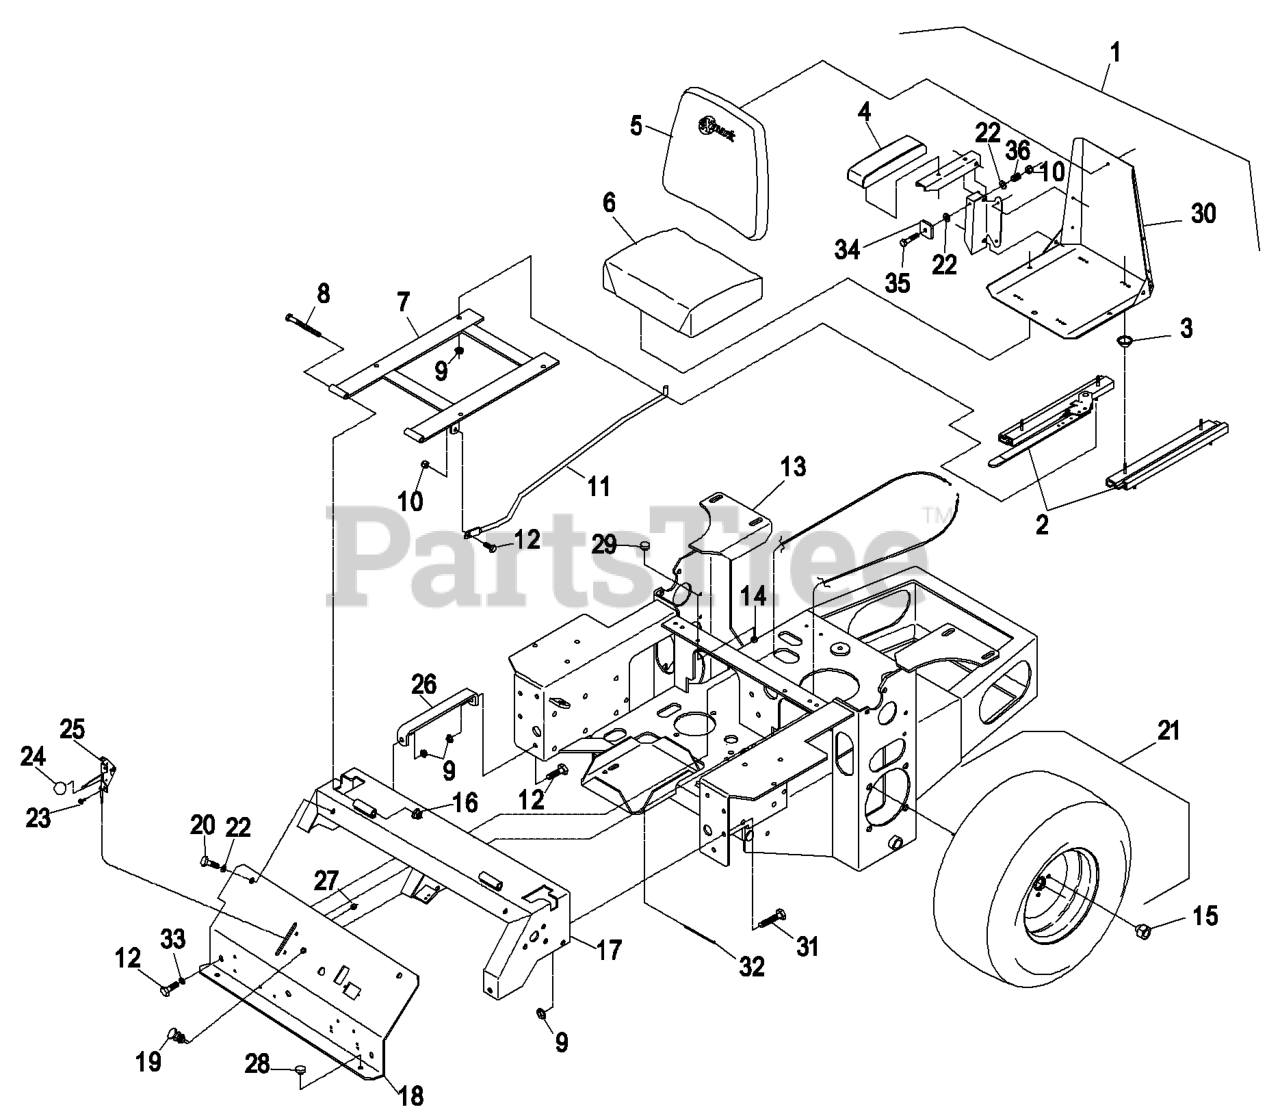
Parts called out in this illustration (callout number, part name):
2	TRACK-SEAT
3	SPACER-TRACK
4	CUSHION,ARMREST RH
8	SCREW-HH
10	NUT-LOCK, NI
11	ROD-RETAINER, SEAT
12	SCREW-HH
14	NUT-LOCK, NI
15	NUT-LUG
16	NUT-LOCK, NI
19	CONTROL-CHOKE
20	SCREW-HH
21	WHEEL AND TIRE ASM
22	WASHER-PLAIN
23	BOLT-CARR
24	KNOB-BALL
25	THROTTLE CABLE ASM
27	NUT-LOCK, NI
30	FRAME-SEAT
31	SCREW-HH
32	TIE-PLASTIC
33	WASHER-FLAT
34	TAB,ARMREST ADJUSTMENT
35	SCREW-HH
36	SPRING-TANK, FUEL
